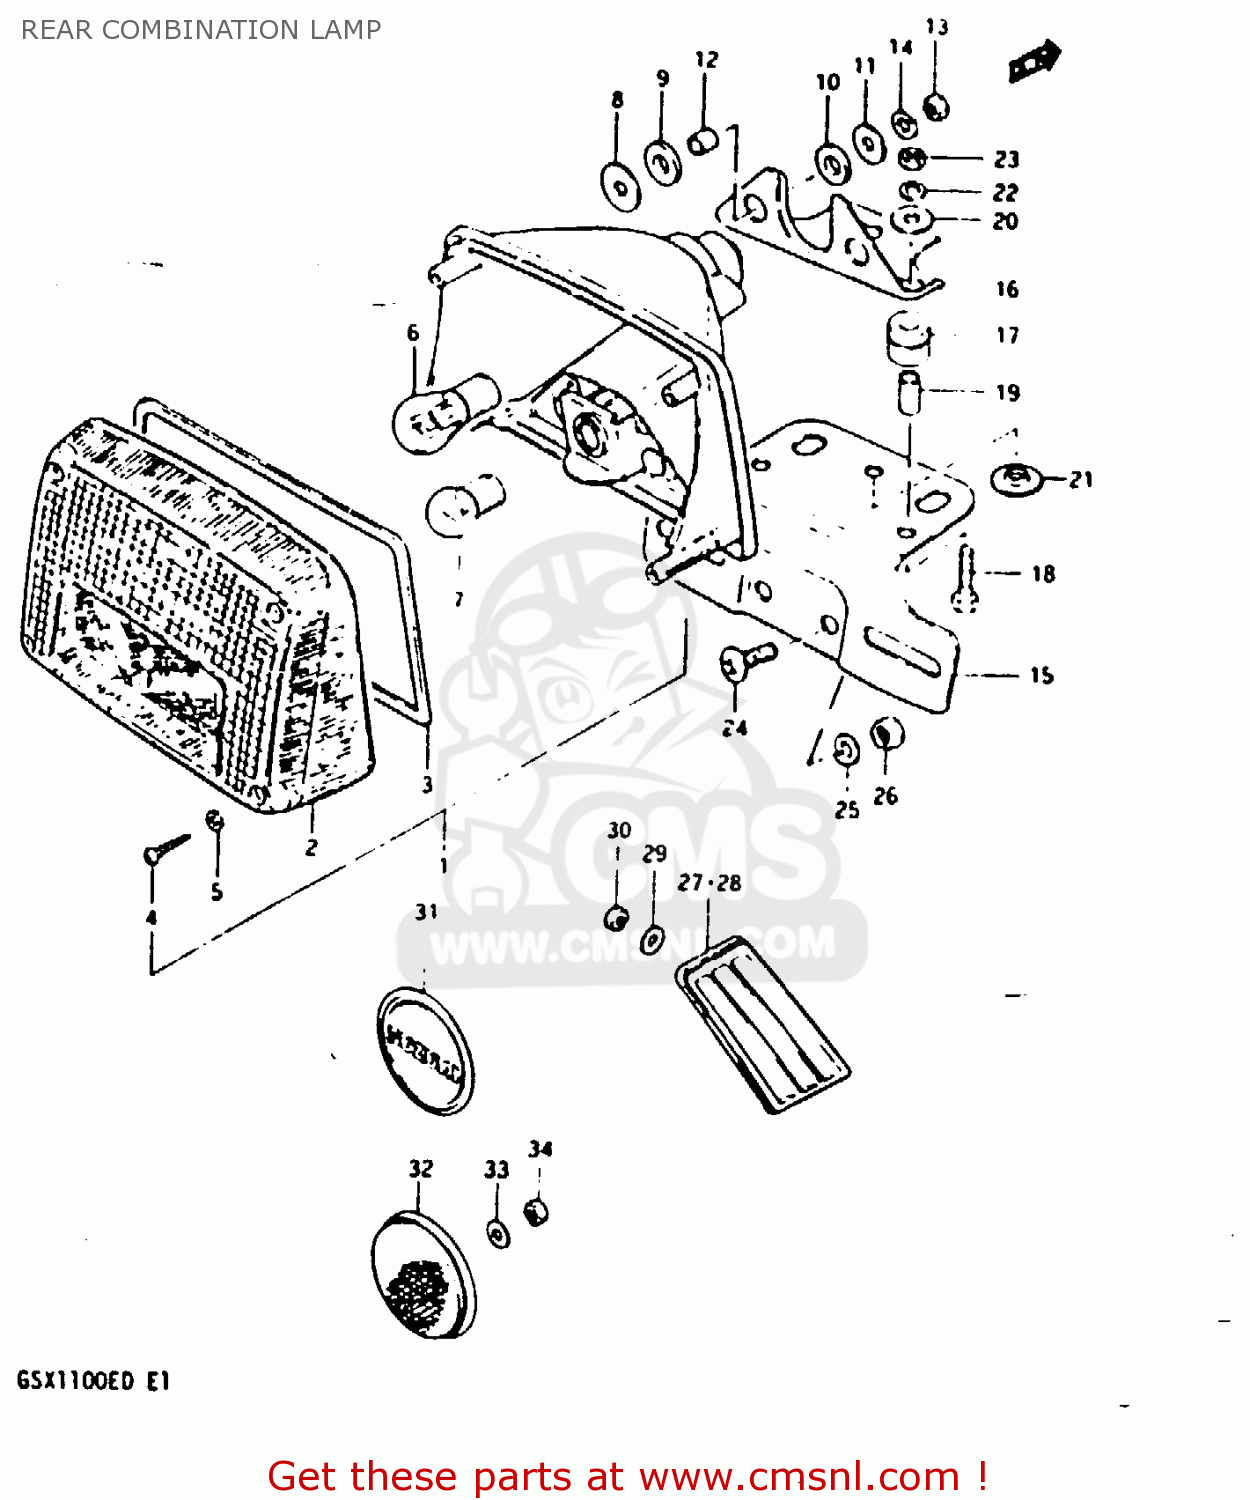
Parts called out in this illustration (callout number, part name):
1	LAMP, REAR COMBINATION
2	LENS,RR COMBI
3	GASKET (NAS)
4	SCREW,REAR COMBINATION LAMP
5	GASKET (NAS)
6	BULB(12V21/5W)
7	BULB
8	WASHER
9	CUSHION
10	CUSHION
11	WASHER(6,5X22X1.6)
12	SPACER(6.1X9X7.5)
13	NUT
14	LOCK WASHER
15	BRACKET, LICENCE PLATE
16	BRACKET,LICENSE PLATE
17	CUSHION, BRACKET
18	BOLT
19	SPACER (6.4X9X15.5)
20	WASHER
21	WASHER
22	LOCK WASHER
23	NUT
24	SCREW
25	LOCK WASHER
26	NUT
27	EMBLEM, REAR SIDE RH
28	EMBLEM, REAR SIDE LH
29	WASHER(5.2X16X1)
30	NUT
